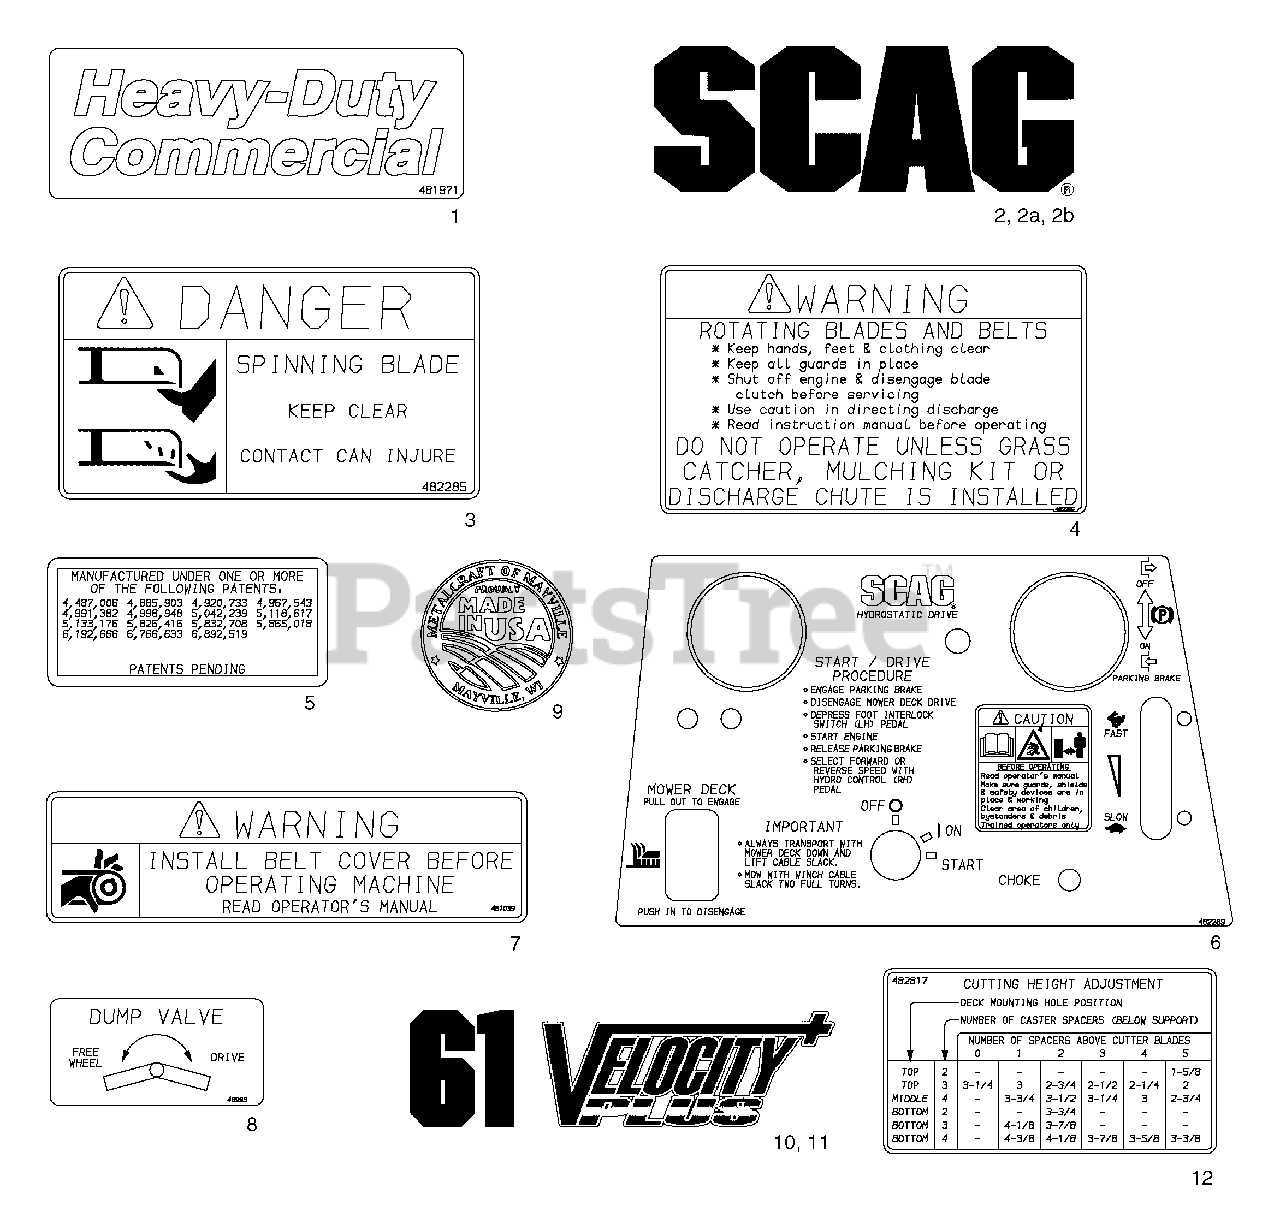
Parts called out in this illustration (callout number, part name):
1	Decal, Heavy Duty Commercial
2	Decal, Scag Logo (Cutter Deck)
3	Decal, Danger-Spinning Blades
4	Decal, Warning-Rotating Blades
5	Decal, Patent
6	Decal, Instrument Panel
7	Decal, Warning-Belt Cover
8	Decal, Dump Valve
9	Decal, Metalcraft-Made In USA
10	Decal, 61 Velocity Plus
11	Decal, 72 Advantage
12	Decal, Height of Cut
